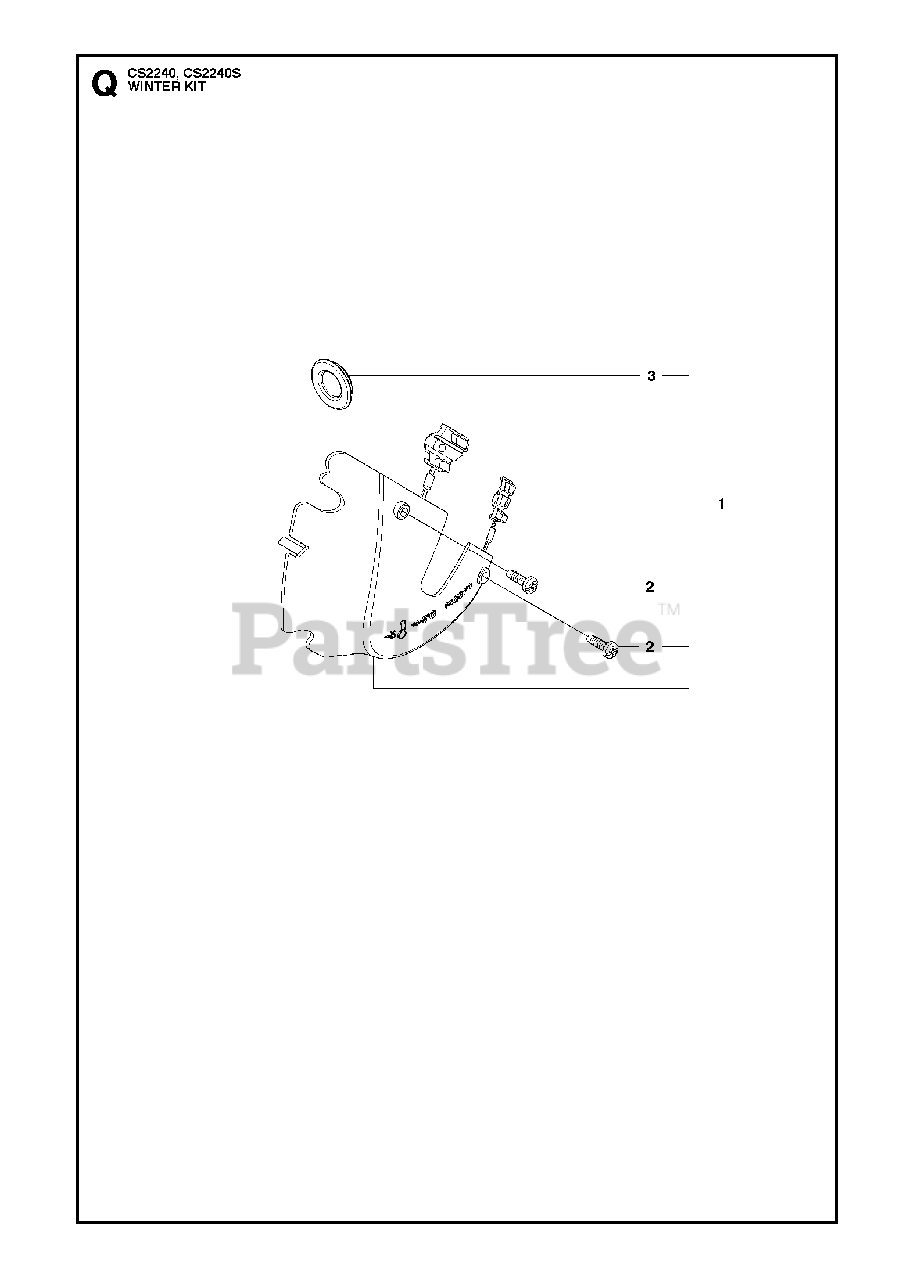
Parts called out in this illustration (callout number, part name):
1	WINTER KIT
2	SCREW
3	PLUG
